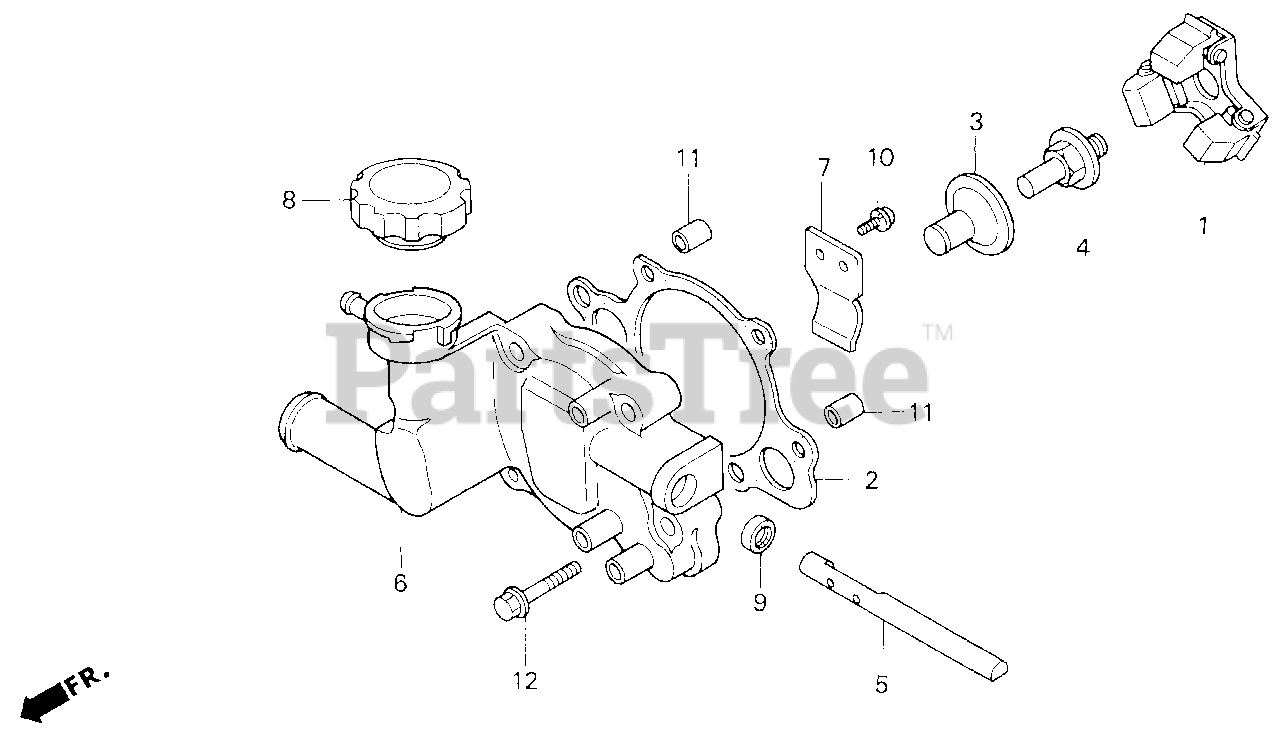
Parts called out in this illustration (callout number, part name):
1	WEIGHT, GOVERNOR
2	GASKET, GOVERNOR COVER
3	SLIDER, GOVERNOR
4	SHAFT, GOVERNOR
5	SHAFT, GOVERNOR
6	COVER, GOVERNOR
7	FORK, GOVERNOR
8	CAP, RADIATOR (TOYO)
9	OIL SEAL (10X16X4.5)
10	SCREW-WASHER (5X12)
11	PIN A, DOWEL (8X14)
12	BOLT, FLANGE (6X35)
